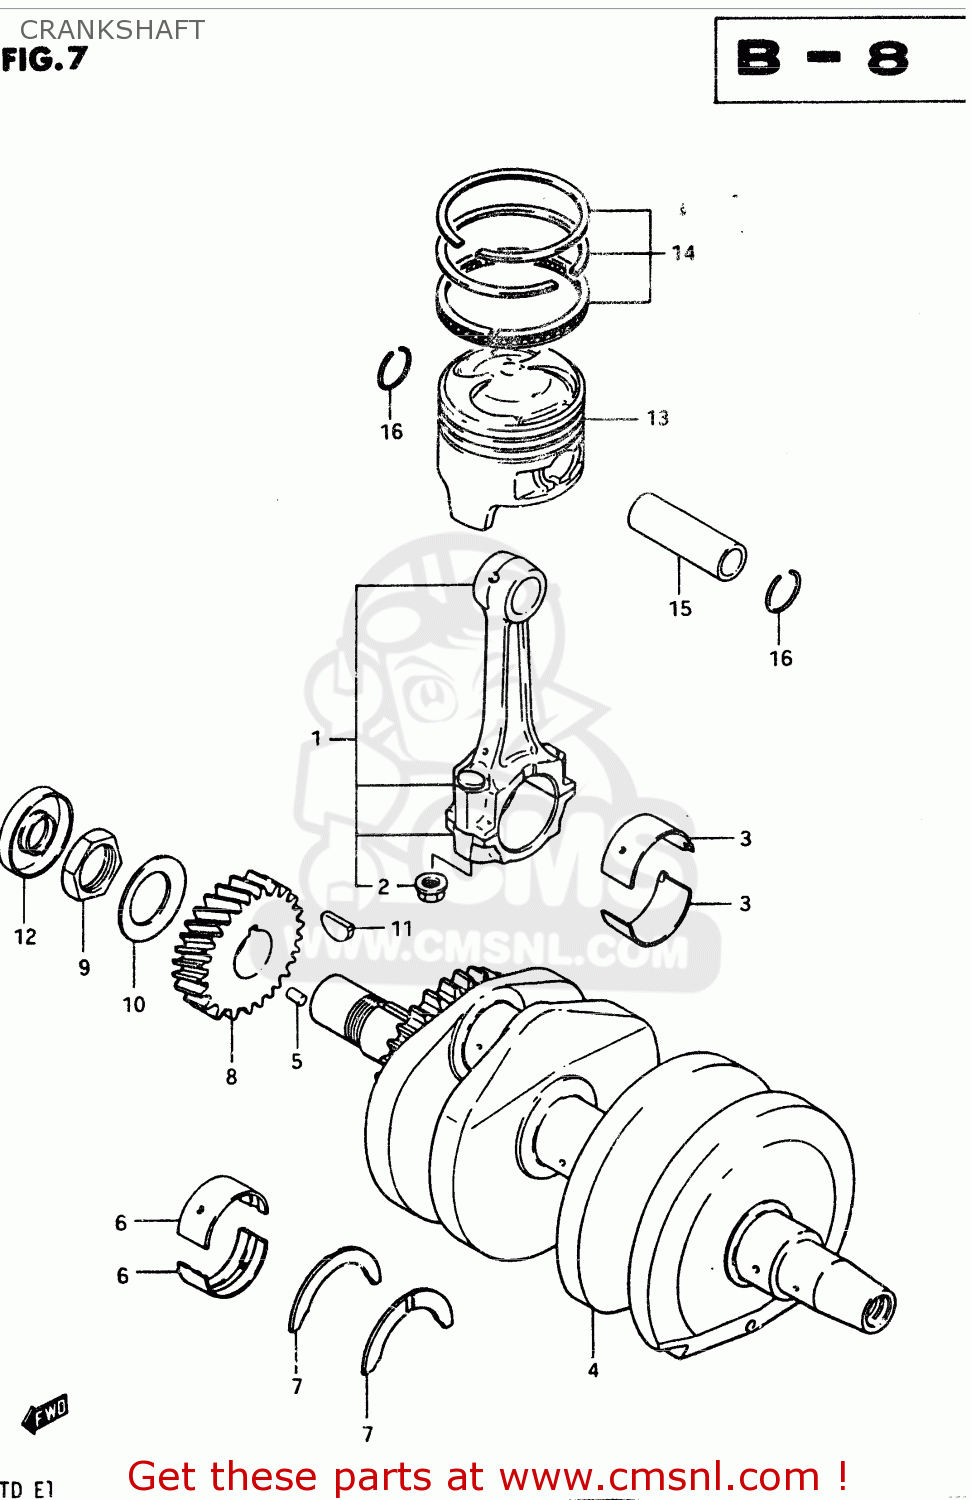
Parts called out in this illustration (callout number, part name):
1	ROD ASSEMBLY,CONNECTING
2	NUT
3	BEARING,CRANK PIN
4	CRANKSHAFT
5	PIN 3X5
6	METAL CRANKSHAFT
7	BEARING,CRANK THRUST
8	GEAR,PRIMARY DRIVE NO.28
9	NUT
10	WASHER
11	KEY
12	OIL SEAL
13	PISTON (STD)
14	RING SET,PISTON
15	PIN,PISTON
16	CIRCLIP,PISTON PIN
